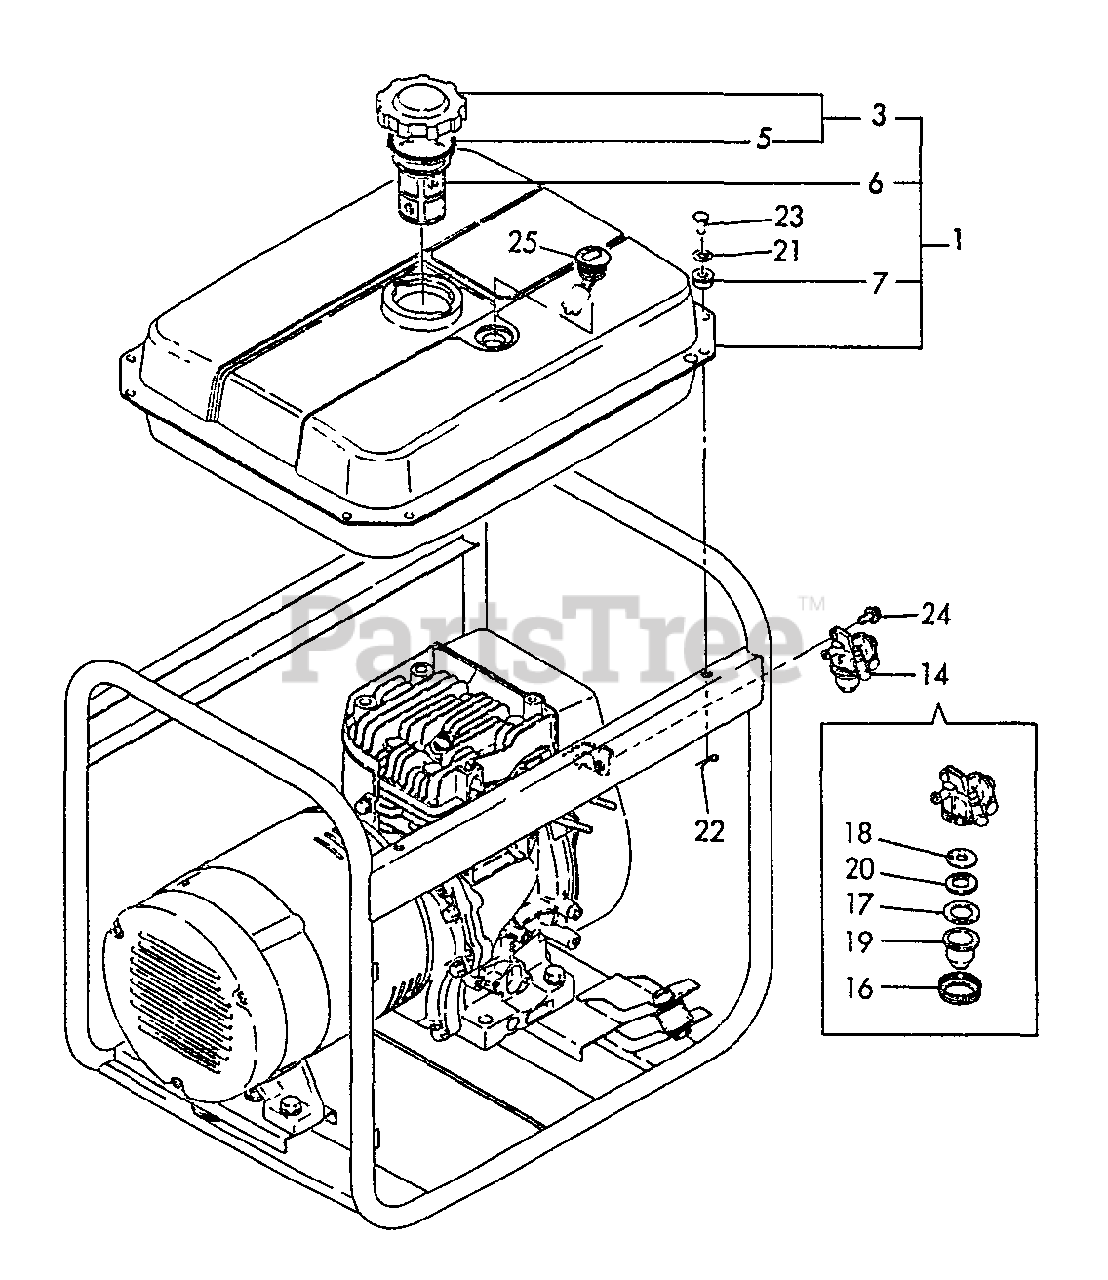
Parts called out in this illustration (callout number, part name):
1	FUEL TANK ASSY
3	CAP ASSY
5	GASKET
6	STRAINER, FUEL
7	GROMMET
14	FUEL COCK ASSY
16	RETAINER
17	GASKET
18	FILTER, FUEL
19	BOWL, STRAINER
20	PLATE
21	WASHER
22	PIN - 6 -- SNAP
23	PIN - 6X14
24	BOLT - 6X8 -- PLATED
25	GAUGE, FUEL
